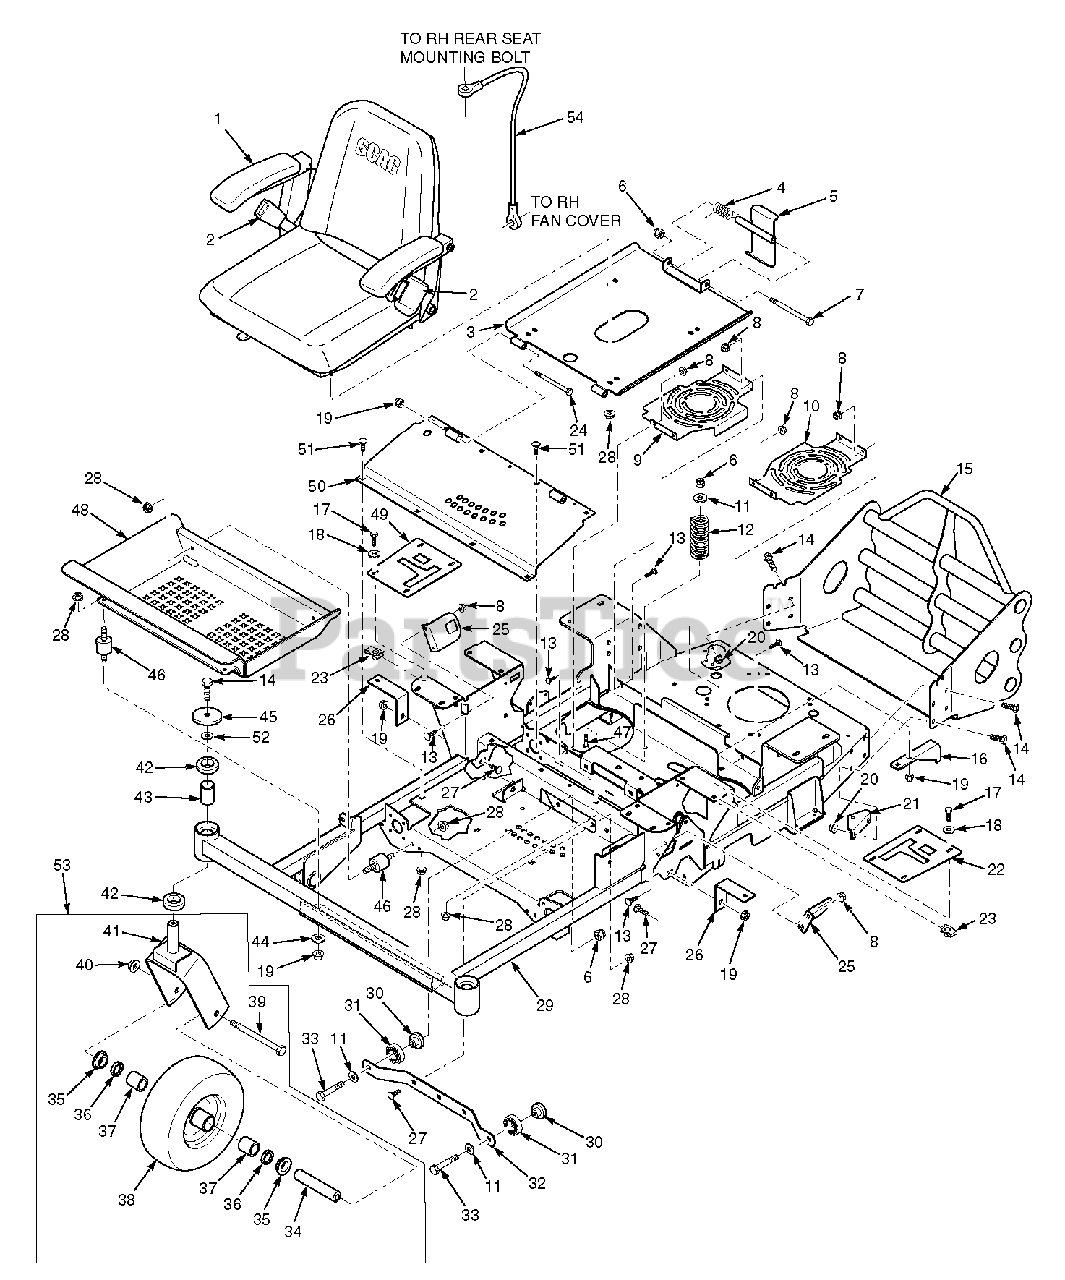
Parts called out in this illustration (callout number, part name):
1	Seat Assembly
1	Back Cushion
1	Bottom Cushion
1	Arm Rest Kit
1	Seat Pan
1	Seat Adjustment Kit
2	Seat Belt Assembly, Retractable
2	Hardware Package, Mounting
3	Seat Base w/Decal
4	Spring, Seat Latch
5	Seat Latch
6	Nut, Elastic Stop 3/8-16
7	Bolt, Hex Head 3/8-16 x 6"
8	Nut, Serrated Flange 1/4-20
9	Cover, Fan RH
10	Cover, Fan LH
11	Flatwasher, 3/8-.391 x .938 x .105
12	Spring, Seat
13	Bolt, Carriage 1/4-20 x 1"
14	Bolt, Hex Head 3/8-16 x 1"
15	Rear Bumper
16	Bracket, Anti-Rotation
17	Bolt, Hex Head 1/4-20 x 1"
18	Flatwasher, 1/4-.312 x .750 x .065
19	Nut, Elastic Stop 5/16-18
20	Nut, Serrated Flange 3/8-16
21	Bracket, Dump Valve
22	Control Plate LH
23	U-Nut 1/4-20
24	Bolt, Hex Head 5/16-18 x 3-3/4"
25	Bracket, Switch Mount
26	Bracket, Tank Mount
27	Bolt, Carriage 5/16-18 x 3/4"
28	Nut, Serrated Flange 5/16-18
29	Main Frame w/Decals
30	Spacer, Bearing
31	Bearing
32	Support, Deck Guide
33	Bolt, Hex Head 3/8-16 x 1-3/4"
34	Sleeve, Front Caster Wheel
35	Bearing
36	Seal, 1 x 1.375 x .25
37	Bearing
38	Caster Wheel Assembly
38	Tire, 11 x 4-5.00 2-Ply
38	Rim, 5 x 3.25 w/Valve
39	Bolt, Hex Head 1/2-13 x 6-1/2"
40	Nut, Elastic Stop 1/2-13
41	Yoke, Caster Wheel
42	Bearing
43	Spacer, Caster Bearing
44	Flatwasher, 5/16-.375 x .875 x .083
45	Flatwasher, 3/8-.406 x 2.25 x .188
46	Rubber Isolator
47	Bolt, Carriage 3/8-16 x 1-1/4"
48	Footplate Weldment
49	Control Plate RH
50	Weldment, Deck Lift Cover
51	Bolt, Carriage 5/16-18 x 1/2'
52	Flatwasher, 7/16-.50 x 1.250 x .083
53	Caster Wheel Assembly w/Yoke
54	Cable, Seat Stop
